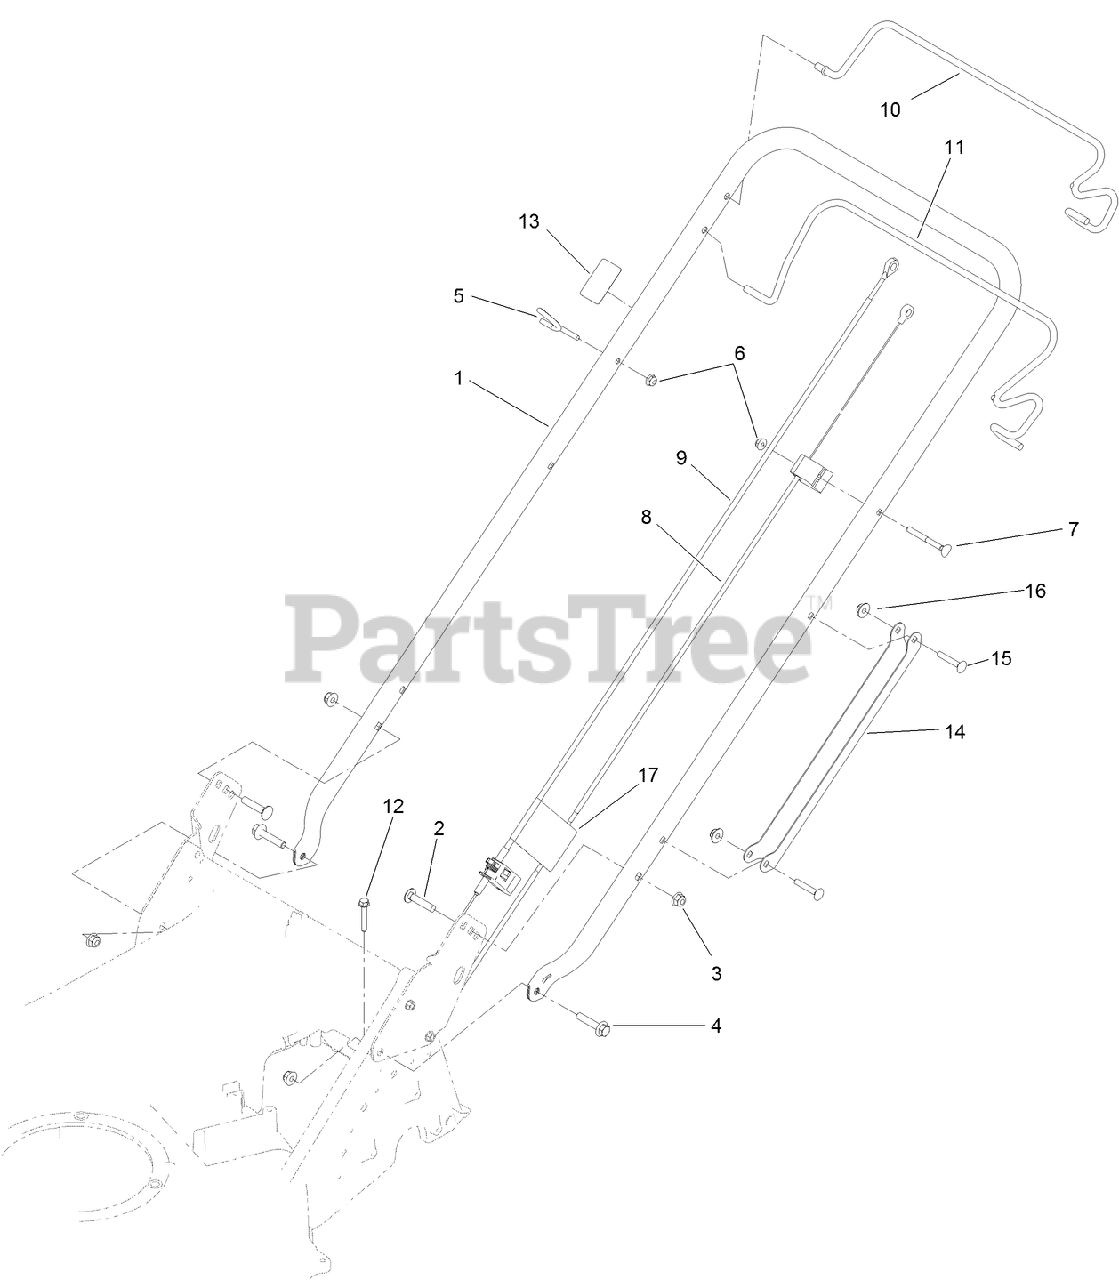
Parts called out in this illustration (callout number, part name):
1	HANDLE
2	BOLT-CARR
3	NUT-HF, NI
4	SCREW-HHF
5	GUIDE-ROPE
6	NUT-HF
7	SCREW-HANDLE
8	CABLE-BRAKE
9	CABLE-TRACTION
10	BAIL-TRACTION
11	BAIL-BRAKE
12	SCREW-HWH
13	DECAL-PRIMER
14	GUARD-CABLE, HANDLE
15	SCREW-CARR
16	NUT-HF
